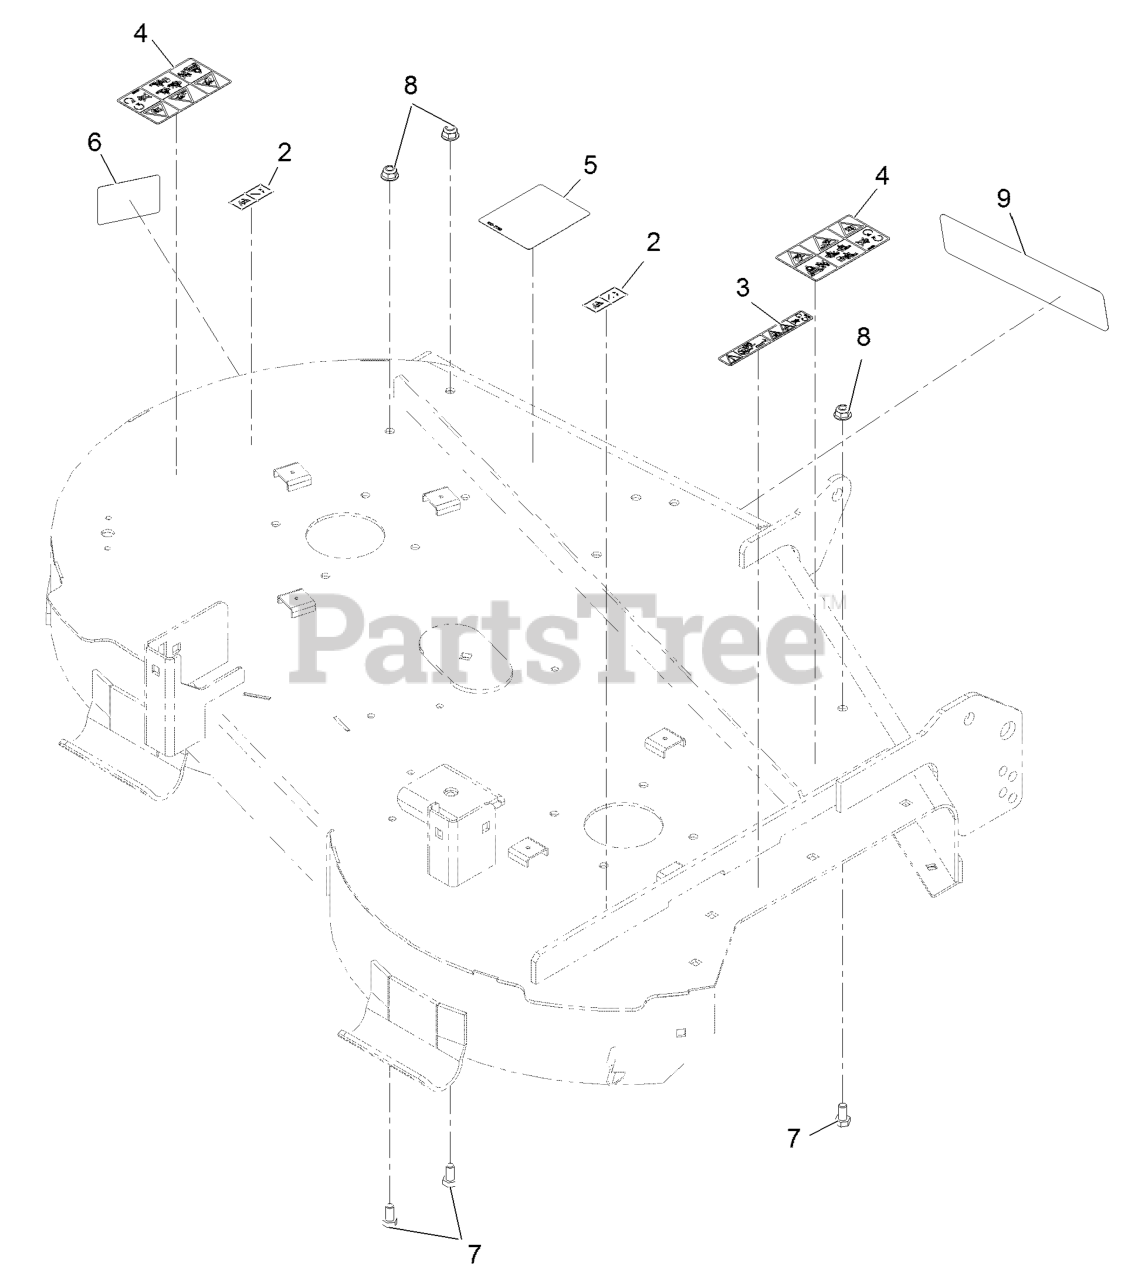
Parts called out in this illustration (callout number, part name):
2	DECAL-DANGER
3	DECAL-DANGER
4	DECAL-DANGER
5	DECAL-ROUTING, BELT
6	DECAL-SCALP, ANTI
7	SCREW-HH
8	NUT-HF, NI
9	Decal-Series 2 - 42
